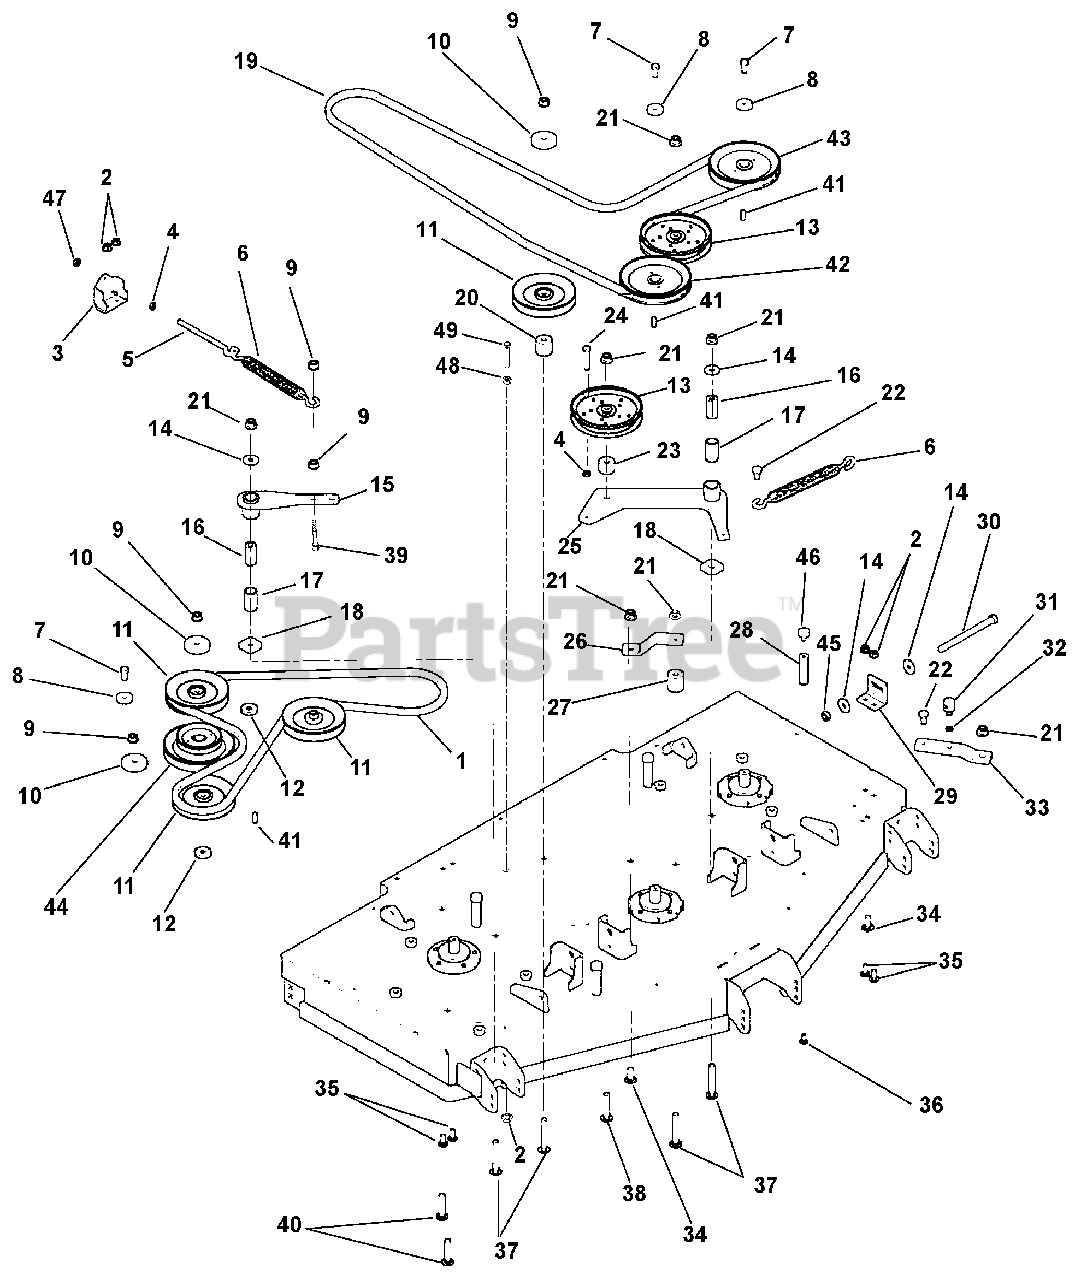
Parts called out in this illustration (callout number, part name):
1	Belt, BB
2	Nut, Locking Nylon Flange .38-16
3	Bracket, Spring Mount
4	Nut, Hex Jam
5	Bolt, .38-16 x 6.00 .62 Diameter Eye
6	Spring, Extension
7	Bolt, Hex .38-16 x 2.75 Grade 8
8	Retainer, Sheave
9	Nut, Locking Top Flange .50-13
10	Cap, Idler Bearing Sealing
11	Sheave, .50" ID x 6.00" OD V-Idler
12	Spacer, .516 x 1.5 x .2894
13	Pulley, Idler Flat 6.75 x .510
14	Washer, Flat Steel .563 x 1.38 x .109
15	Arm, Idler Pivot
16	Bushing, Spacer .502 x .997 x 2.03
17	Bushing, 1.00 x 1.125 x 1.936
18	Washer, Flat .640 x 1.75 x .250
19	V-Belt, HB, Wrapped Clutching
20	Spacer, .516 x 1.5 x 1.345
21	Nut, Locking Nylock Flange .50-13
22	Bolt, Shoulder EP .38-16 x .30 Hex
23	Spacer, .516 x 1.5 x .97
24	Bolt, Hex .38-16 x 2.25
25	Arm, Idler Pivot
26	Bracket, Idler Mount
27	Spacer, .516 x 1.50 x 1.517
28	Nut, Coupling .31-18 x 3.00
29	Bracket, Spring Mount, Left Hand
30	Bolt, .5-13 x 7.00
31	Trunnion, Spring Adjust .50-13
32	Snap Ring, Retaining External .500 x .050
33	Arm, Spring Tensioner
34	Bolt, Round Head Square Neck .50-13 x 1.25
35	Bolt, Round Head Square Neck .38-16 x 1.00
36	Bolt, Round Head Square Neck .31-18 x .75 Loctite
37	Bolt, Round Head Square Neck .50-13 x 3.50
38	Bolt, Round Head Square Neck .50-13 x 2.75
39	Bolt, Hex .50-13 x 2.50
40	Bolt, Round Head Square Neck .50-13 x 2.50
41	Key, Square .25 x .25 x 1.00
42	Pulley, Double 1.0 x 6.75 O.D.
43	Pulley, "V" 1.0 x 6.75 O.D.
44	Pulley, Double 1.0 x 6.75 x 4.25
45	Nut, Jam .50-13
46	Bumper, Rubber
47	Nut, Locking Center Jam .375-16
48	Nut, Spin Lock Flange .375-16
49	Bolt, Hex .38-16 x 3.50 Grade 5
